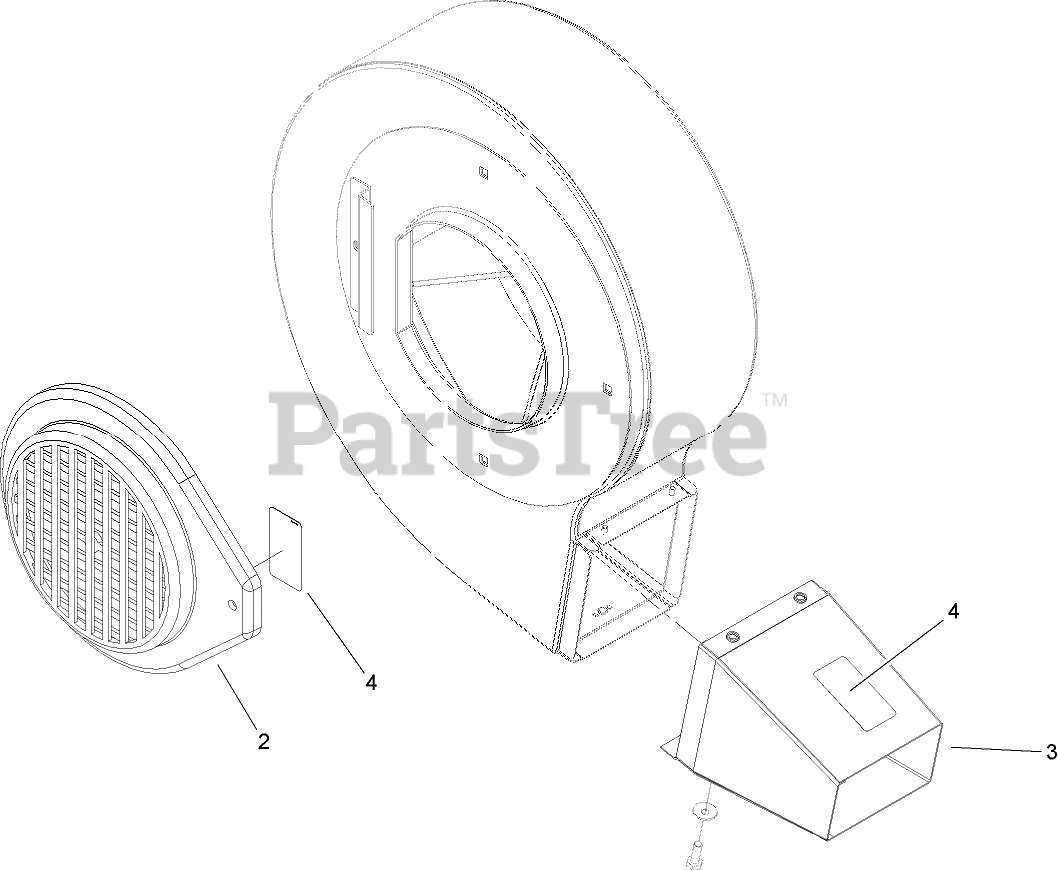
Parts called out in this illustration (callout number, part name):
2	INTAKE-BLOWER
3	BLOWER EXHAUST ASM
4	DECAL-CAUTION, BAG
